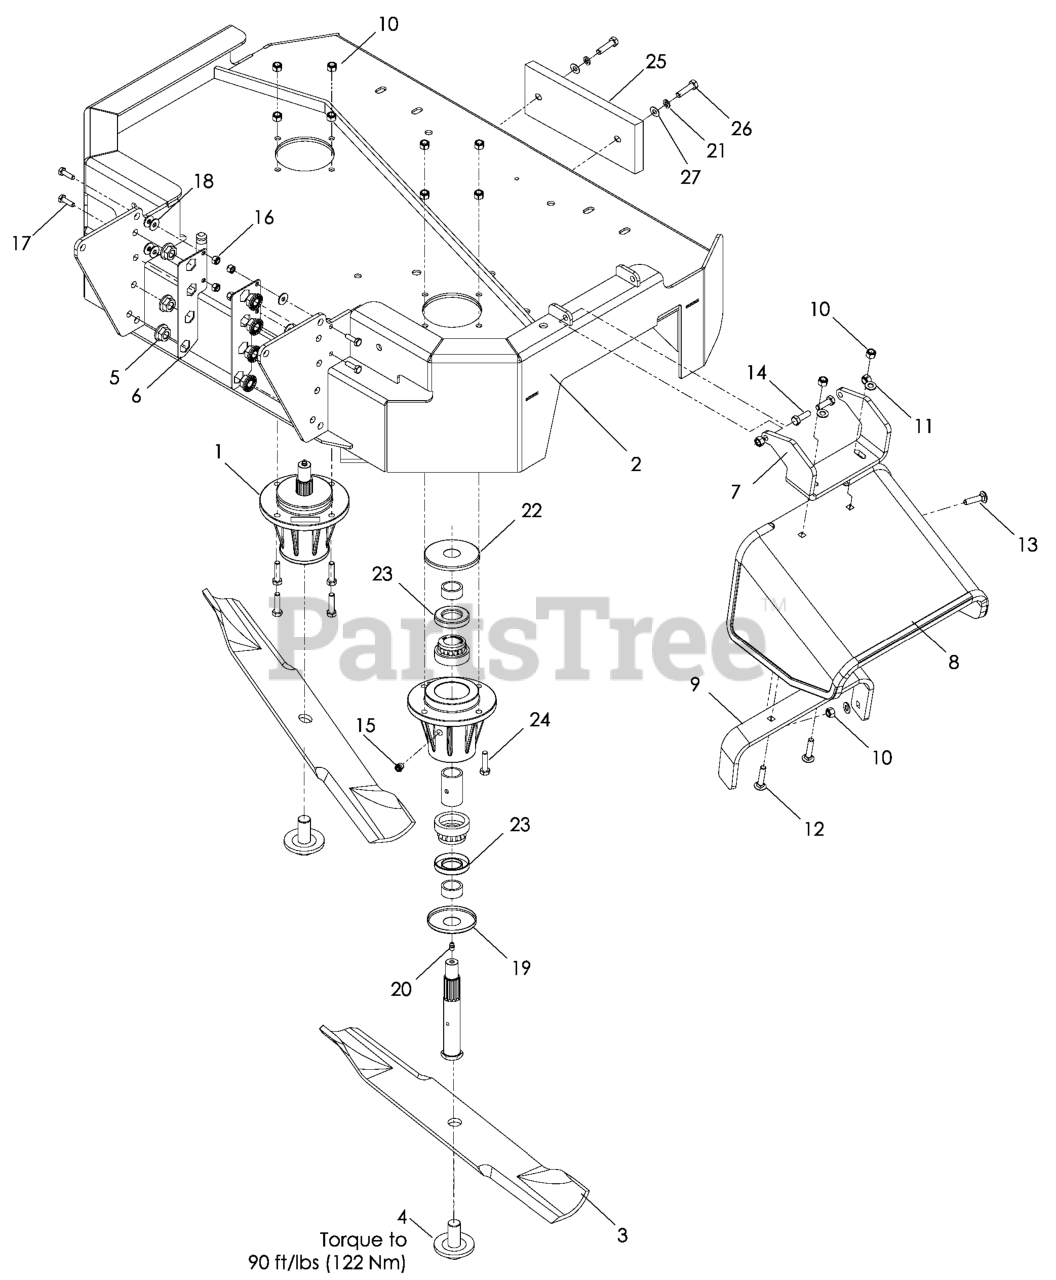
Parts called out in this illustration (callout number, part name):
1	HOUSING ASM, 72
2	DECK SVC WH3615 W/DECALS
3	BLADE OEM 18"
4	BLADE BOLT/WASHER
5	NUT FLANGE 1/2-13 GR 5
6	PLATE NUT - PAINTED
7	HINGE CHUTE - BLACK
8	CHUTE, RUBBER DISCHARGE WB
9	BRKT, REINF-CHUTE WB
10	NUT 5/16 NYLOC
11	FLAT WASHER 5/16 SAE
12	RHSNB 5/16-18 X 1-1/2 GR 5 ZD
13	BOLT, CARRIAGE 5/16X1-1/4
14	HCS 5/16C X 1
15	PLUG-VENTED
16	NUT.1/4-20.HEX.NYLOC.ZD
17	HCS 1/4-20X7/8 GR5
18	WASHER 1/4 FLAT
19	BOTTOM DUST CAP
20	ZERK
21	WASHER 1/2" SPLIT LOCK
22	TOP DUST CAP
23	SHAFT SEAL
24	HCS 5/16C X 1 1/4
25	WEIGHT, COUNTER, ORANGE
26	HCS 1/2-13 X 1-1/2 GR 5 ZD
27	WASHER 1/2" FLAT
